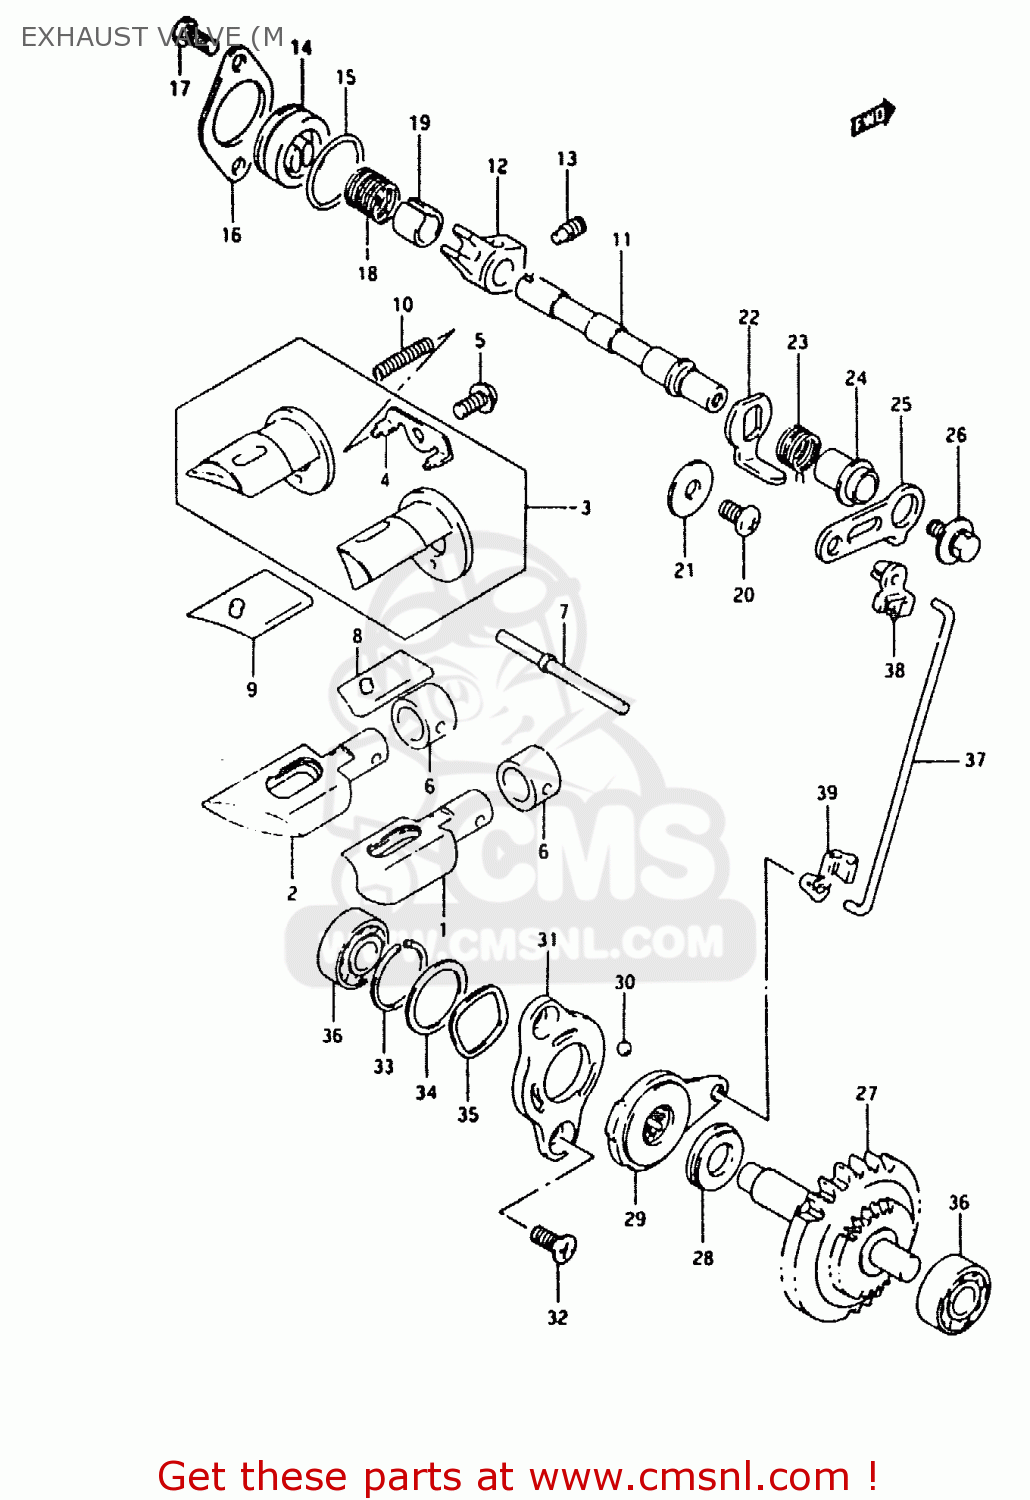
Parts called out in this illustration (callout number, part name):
1	VALVE,EXHAUST,LOWER,RIGHT
2	VALVE,EXHAUST LOW,L
3	GUIDE SET,EXHAUST VALVE
4	STOPPER,EXHAUST VALVE NO.2
5	SCREW 5X12
6	SPACER,EXHAUST VALVE
7	PIN,EXHAUST VALVE 48.5MM
8	VALVE,EXHAUST MIDDLE,R
9	VALVE,EXHAUST MIDDLE,L
10	SPRING
11	SHAFT,EXHAUST VALVE
12	ARM,EXHAUST VALVE SHAFT
13	SCREW(6X10)
14	CAP,EXHAUST VALVE
15	O RING(D:1.9,ID:22.6)
16	RETAINER,EXHAUST VALVE
17	BOLT
18	SPRING
19	SPACER,EXHAUST VALVE SPRING
20	BOLT
21	WASHER
22	LEVER,EXHAUST VALVE NO.2
23	SPRING
24	SPACER,EXHAUST VALVE
25	LEVER,EXHAUST VALVE NO.1
26	BOLT(5X12)
27	GOVERNOR ASSEMBLY,EXHAUST
28	BEARING(10X22X2.8)
29	ACTUATOR,EXHAUST VALVE
30	BALL
31	STARTER,EXHAUST VALVE ACTUATOR
32	SCREW(5X10)
33	CIRCLIP
34	SHIM(19.1X25X0.3)
35	WASHER
36	BEARING(8X22X7)
37	ROD,EXHAUST VALVE
38	BUSH,EXHAUST VALVE ROD NO.1
39	BUSH,EXHAUST VALVE ROD NO.2
41	BUSH,EXHAUST VALVE ROD NO.2
